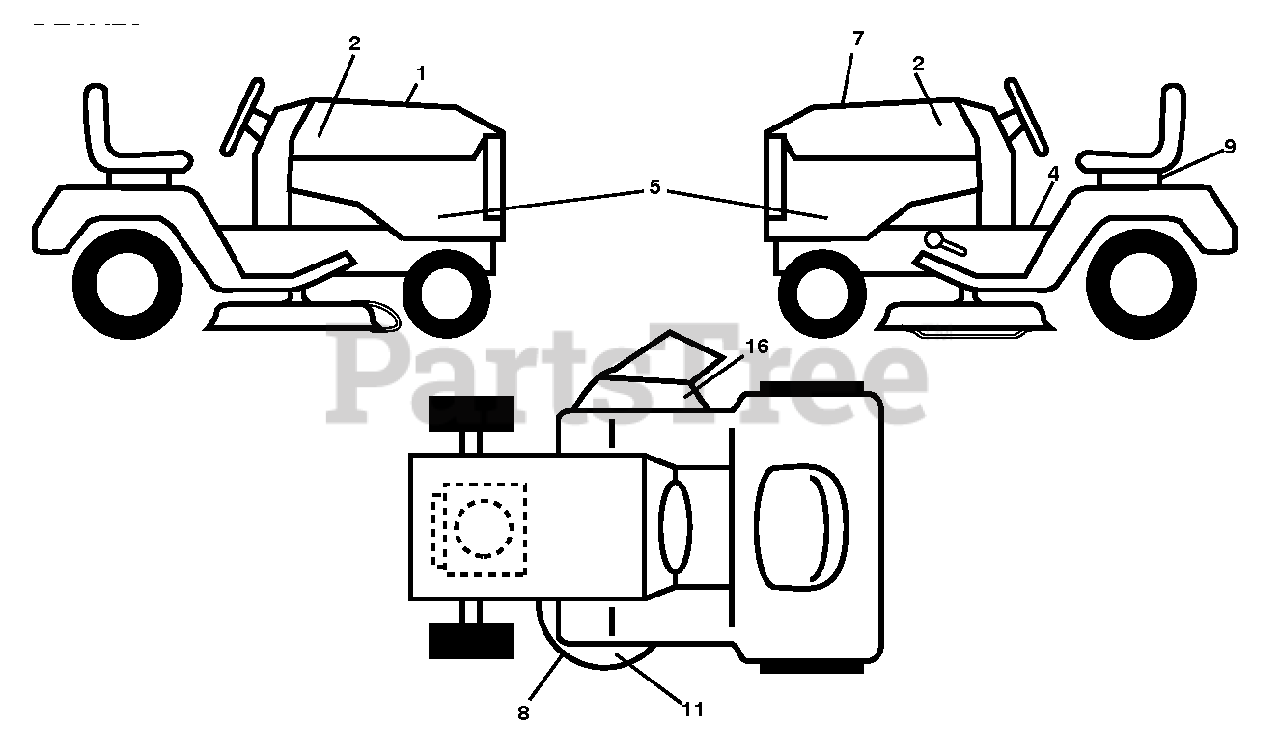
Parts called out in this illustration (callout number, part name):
1	DECAL.RPL.KH.SV591.TLW.42.GENT
2	DECAL.BADGE.170MM.TEXTLOGO.
4	DECAL.FENDER.WARNING.ENGLISH
5	DECAL.SIDE.PANEL.YTA19K42
7	DECAL.WARNING.CUST.RESP.E85.
8	DECAL.V-BELT.SCH.42/46"MEC/ELE
9	DECAL BTRY SYMBOLS
11	DECAL POP ARMORPROTECTORDECK
16	DECAL.MOWER.WARN.KEEP.HAND.AWY
